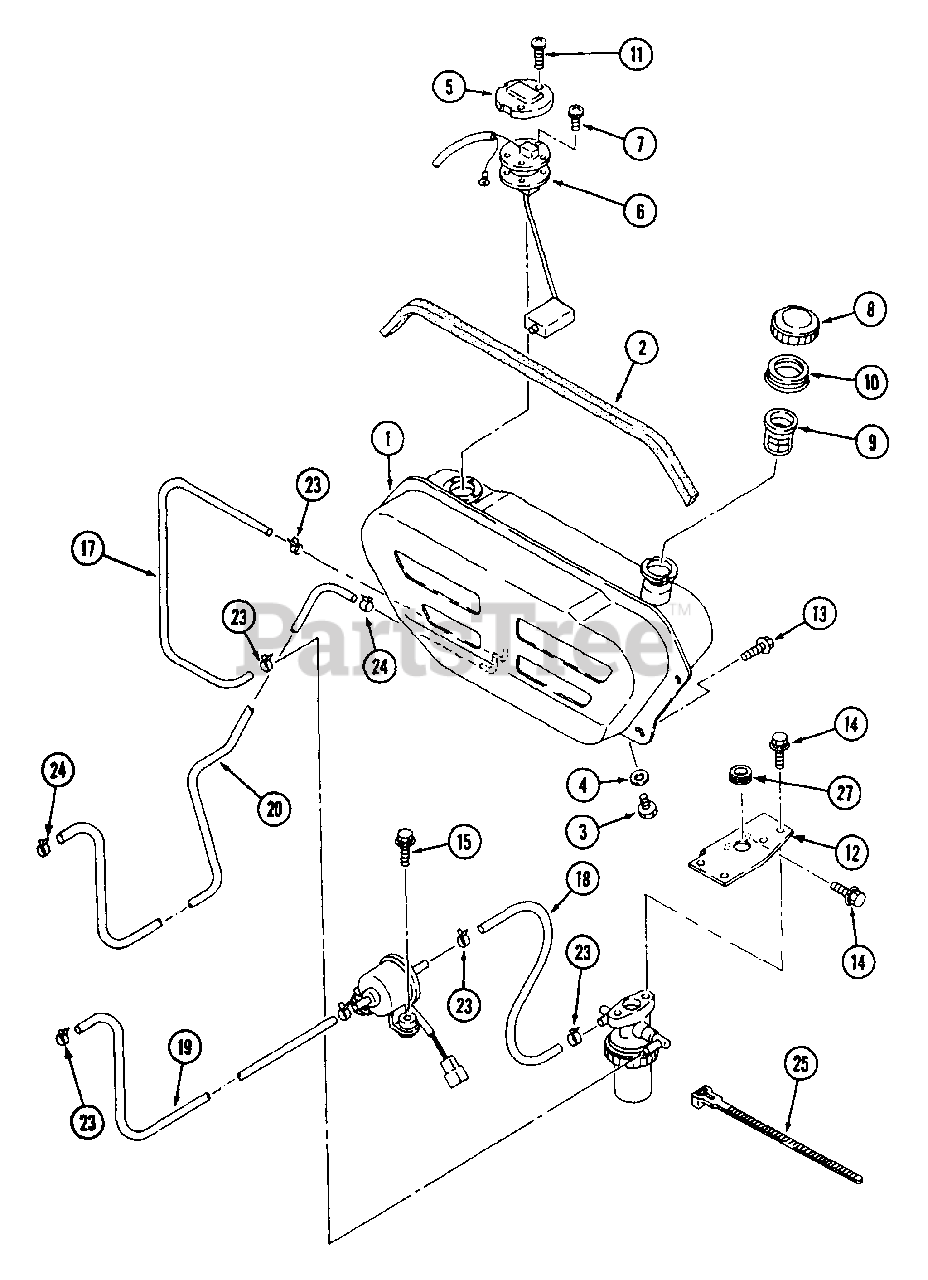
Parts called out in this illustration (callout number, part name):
5	Cover, Fuel Unit
12	Bracket, Filter
15	Bolt
